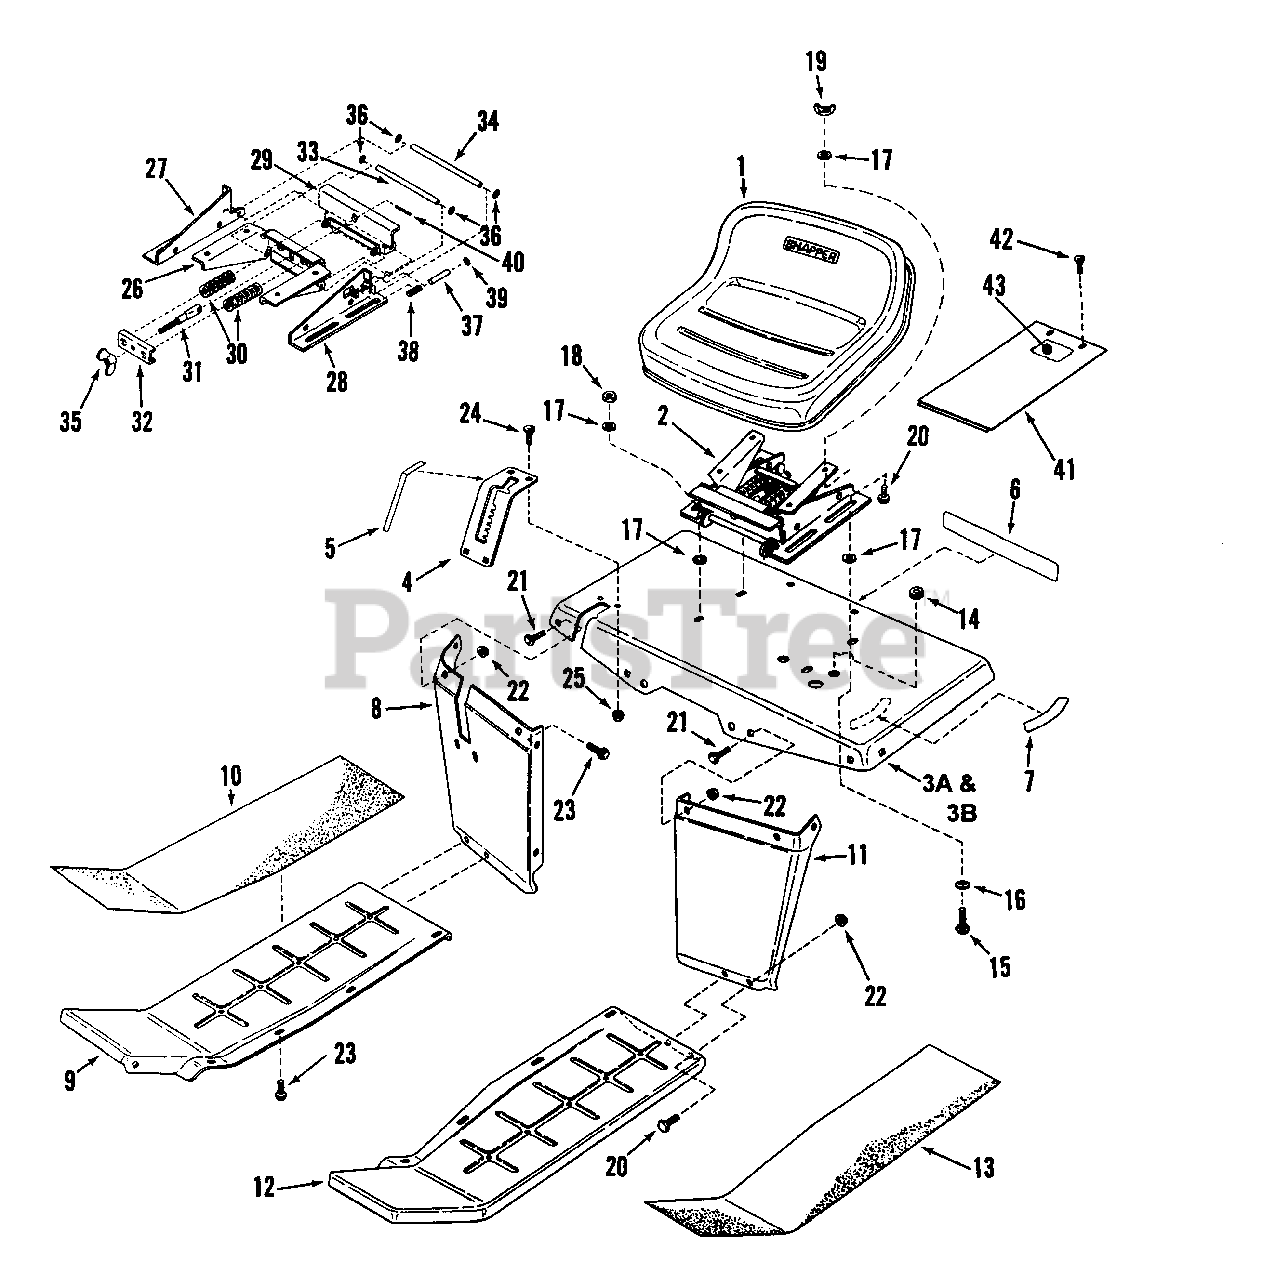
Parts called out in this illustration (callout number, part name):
1	SEAT, Operator's
2	ASSEMBLY, Seat Suspension
3A	FENDER, Rear
3B	FENDER, Rear w/access hole
4	DETENT,Shift
5	DECAL, Speed Shift
6	DECAL, SNAPPER
7	DECAL, HI-LOW RANGE (Shift)
8	EXTENSION, Right Side Fender
9	PANEL, Right Side Step
10	TREAD, Right Side (Non-Skid)
11	EXTENSION, Left Side Fender
12	PANEL, Left Side Step
13	TREAD, Left Side (Non-Skid)
14	GROMMET, Split
15	BOLT, 5/16-18 x 1" Square Neck Carriage
16	RETAINER, 5/16 Bolt
17	WASHER, 5/16" x 1-1/4" x 3/32" Flat
18	NUT, 5/16-18 Hex Center Lock, Grade B or 5
19	WING-NUT, 5/16-18
20	BOLT, 5/16-18 x 1/2" Hex Flange Lock, Grade 5
21	BOLT, 5/16-18 x 1/2" Short Neck Carriage, Grade 5
22	NUT, 5/16-18 Hex Flange Lock, Grade 5
23	SCREW, 5/16-18 x 5/8" Self-Tap
24	BOLT, 1/4-20 x 1/2" Short Neck Carriage, Grade 5
25	NUT, 1/4-20 Hex Flange Lock
26	WELDMENT,Seat Hinge
27	ANGLE, L.H. Mounting
28	ANGLE, R.H. Mounting
29	WELDMENT,Seat Hinge
30	SPRING, Seat
31	ROD, Adjusting
32	RETAINER, Spring
33	PIN, Seat Tilt Hinge
34	PIN, Seat Tilt Hinge
35	WING-NUT, 1/2-13
36	PUSHNUT, 3/8
37	PLUNGER
38	SPRING, Compression
39	RING, Retaining
40	GROOVED PIN, 3/16 x 1-3/4"
41	COVER, Access
42	SCREW, 5/16-18 x 1/2" Hex Washer Self-Tap
43	DECAL, Seat Adjust
